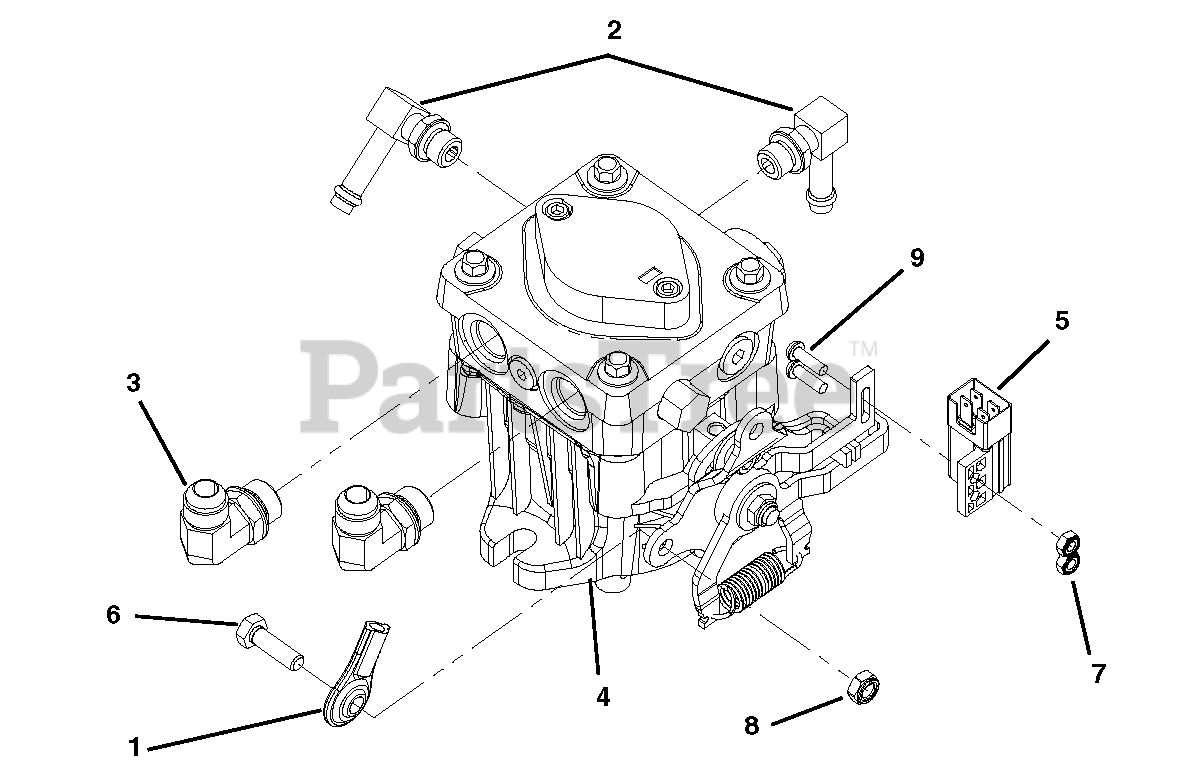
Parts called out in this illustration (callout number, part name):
1	Alignaball, 5/16 RH/Thread
2	Fitting, 90 9/16MOR x 3/8 Hose
3	Fitting
4	Pump, Hydraulic RH
5	Switch, Plunger Diametral Pitch -N.O. -N.C.
6	Bolt, Hex 5/16-18 x 1.00 Grade 5
7	Nut, Locking, Nylon 10-24 w/Insert
8	Nut, Locking, Nylon .312-18
9	Screw, Machine 10-24 x .62 P/HD
NS	Pump Seal Kit
